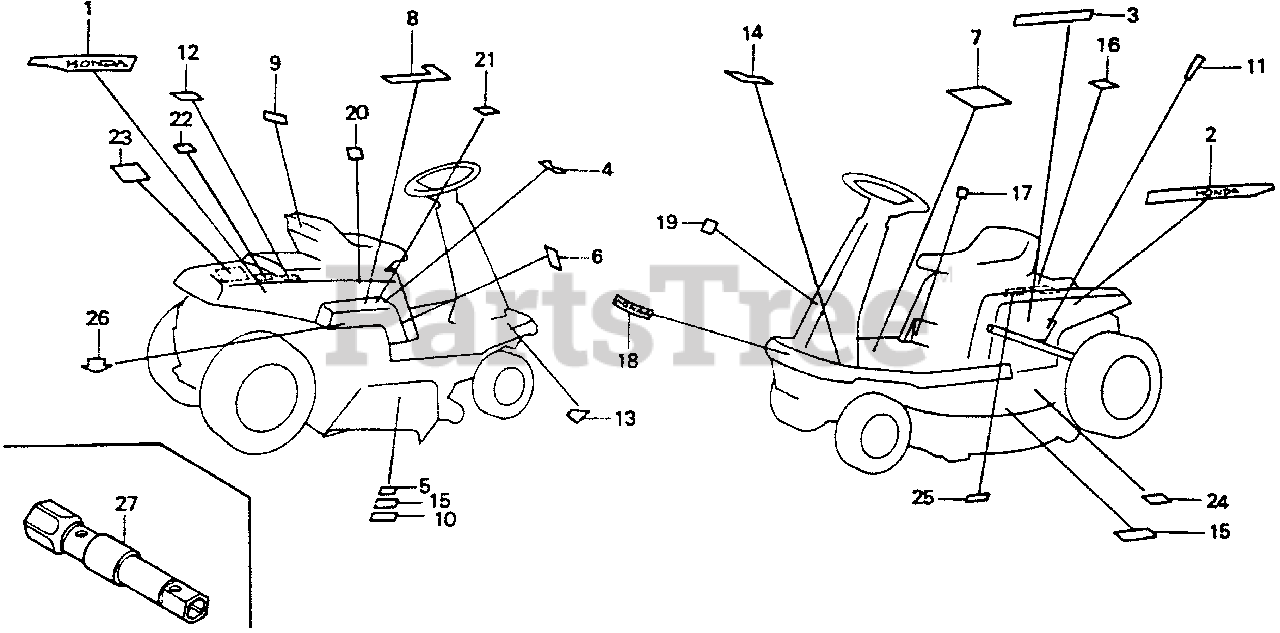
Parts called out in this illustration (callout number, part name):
1	STRIPE, R. SIDE
2	STRIPE, L. SIDE
4	MARK, ENGINE SWITCH (ENGLISH)
6	MARK, THROTTLE (ENGLISH) (NOT AVAILABLE)
7	LABEL, OPERATION (ENGLISH) (NOT AVAILABLE)
8	MARK, GEAR POSITION (ENGLISH)
9	MARK, SEAT
10	LABEL B, WARNING (ENGLISH)
11	MARK, INDICATOR (ENGLISH)
12	LABEL, MAIN FUSE (ENGLISH)
14	MARK, P.T.O. CLUTCH (ENGLISH)
15	LABEL A, WARNING (ENGLISH)
16	LABEL, FUEL WARNING (ENGLISH)
17	MARK, PARKING BRAKE (ENGLISH)
18	MARK, FR. (NOT AVAILABLE)
19	MARK, EMBLEM
21	LABEL, PARKING BRAKE WARNING (ENGLISH)
22	LABEL A, CAUTION
23	LABEL B, CAUTION (ENGLISH)
24	LABEL D, CAUTION (ENGLISH)
25	LABEL, AIR CLEANER CAUTION (ENGLISH)
26	MARK, EX. CAUTION (DUTCH)
27	WRENCH, BOX (P21X12)
